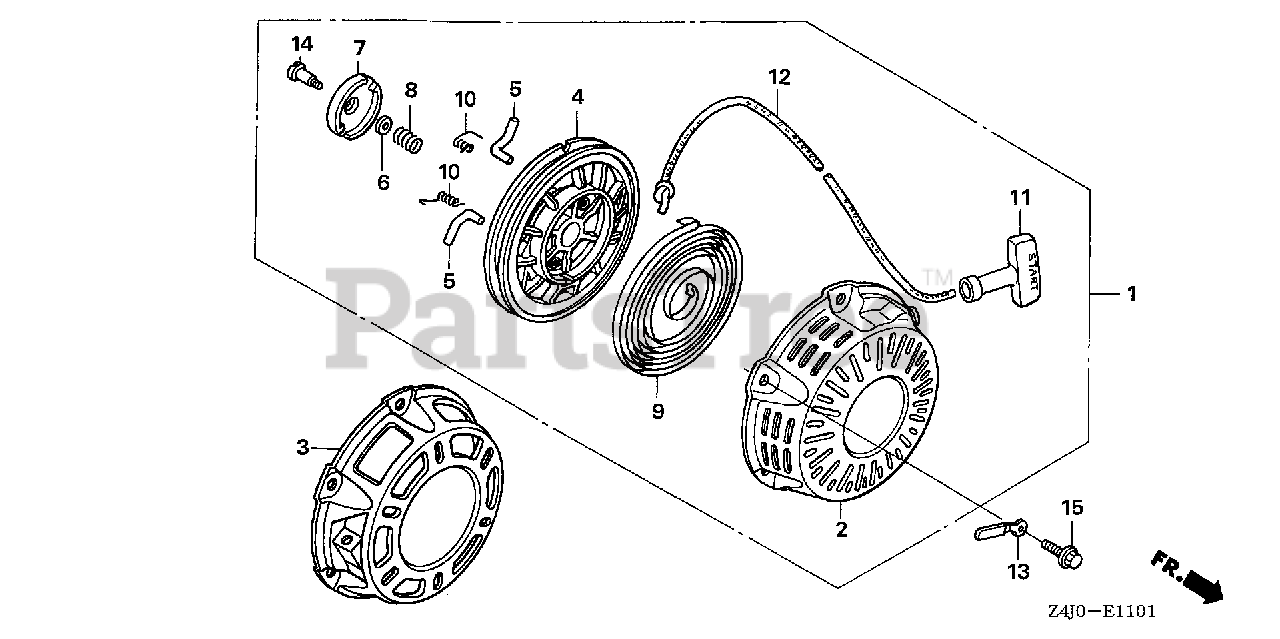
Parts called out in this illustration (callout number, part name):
1	STARTER ASSY., RECOIL *R280* (POWER RED)
2	CASE, RECOIL STARTER *R280* (Honda Code 7346836). (POWER RED)
4	REEL, RECOIL STARTER
5	RATCHET, STARTER
6	PLATE, FRICTION
7	GUIDE, RATCHET
8	SPRING, FRICTION
9	SPRING, RECOIL STARTER
10	SPRING, RETURN
11	GRIP, STARTER
12	ROPE, RECOIL STARTER (#5X55")
14	SCREW, SETTING
15	BOLT, FLANGE (6X10)
